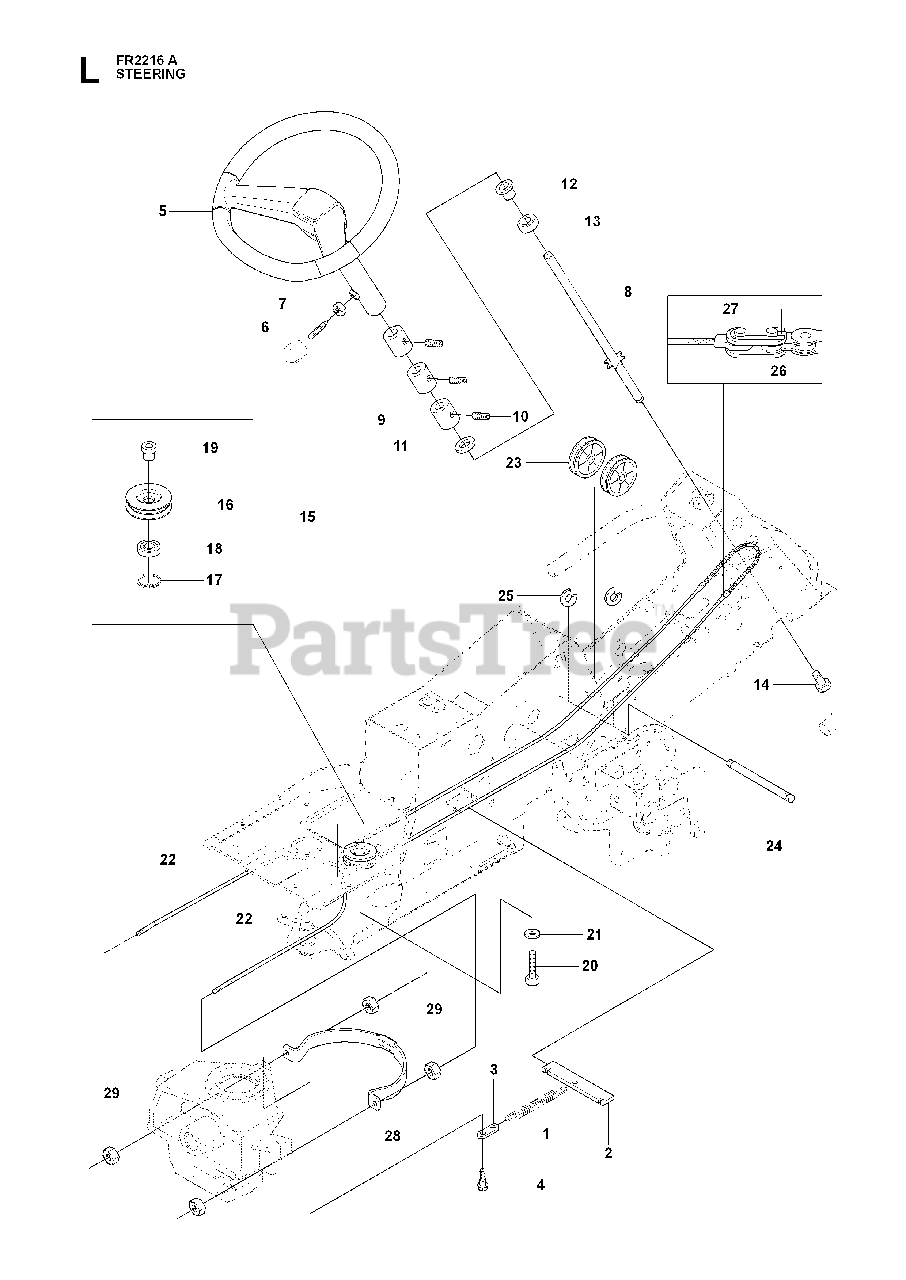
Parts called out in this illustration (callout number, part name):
2	SPRING BRACKET
3	CONNECTOR
5	STEERING WHEEL
7	NUT
8	ROD STEERING ASSY
13	BALL BEARING 6004-2RS1
17	CIRCLIP SGH 47
18	BALL-BEARING 6204-2RS
20	COLLAR SCREW
22	RP STEERING CABLE COMPLETE
25	RETAINING RING
26	STEERING CHAIN
28	WIRE GUIDE
